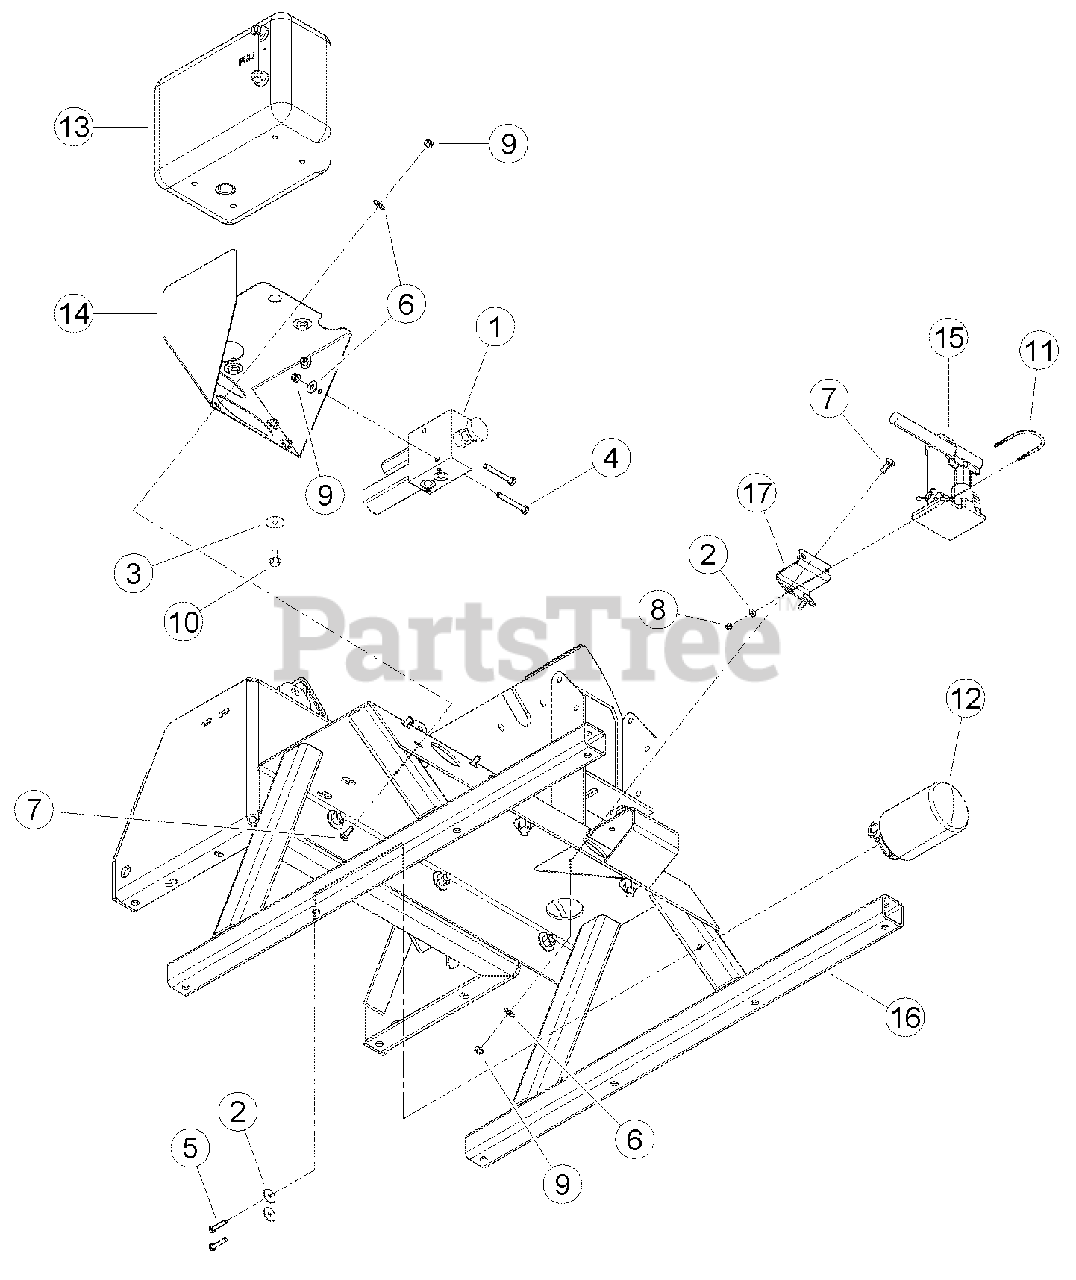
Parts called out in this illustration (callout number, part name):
1	VALVE, HYDRAULIC CONTROL
2	WASHER, 1/4 FLAT ZP
3	WASHER, 3/8 FENDER ZP
4	BOLT, 5/16 X 2-1/2 HEX HD GR5 ZP
5	BOLT, 1/4 X 1-1/4 HCS GR5 ZP
6	WASHER, 5/16 FLAT ZP
7	BOLT, 5/16 X 7/8 CRG GR5 NC ZP
8	NUT, 1/4 NE NYLOCK ZP
9	NUT, 5/16 NE NYLOCK ZP
10	BOLT, 3/8 X 3/4 SERR FLANGE
11	U-BOLT, 1/4 X 1-1/2 PIPE
12	FILTER, SPIN-ON
13	TANK, HYDRAULIC
14	WELDMENT, RESERVIOR BASE
15	JACK, HYDRAULIC 2 TON
16	WELDMENT, PTO STAND
17	MOUNT, JACK
